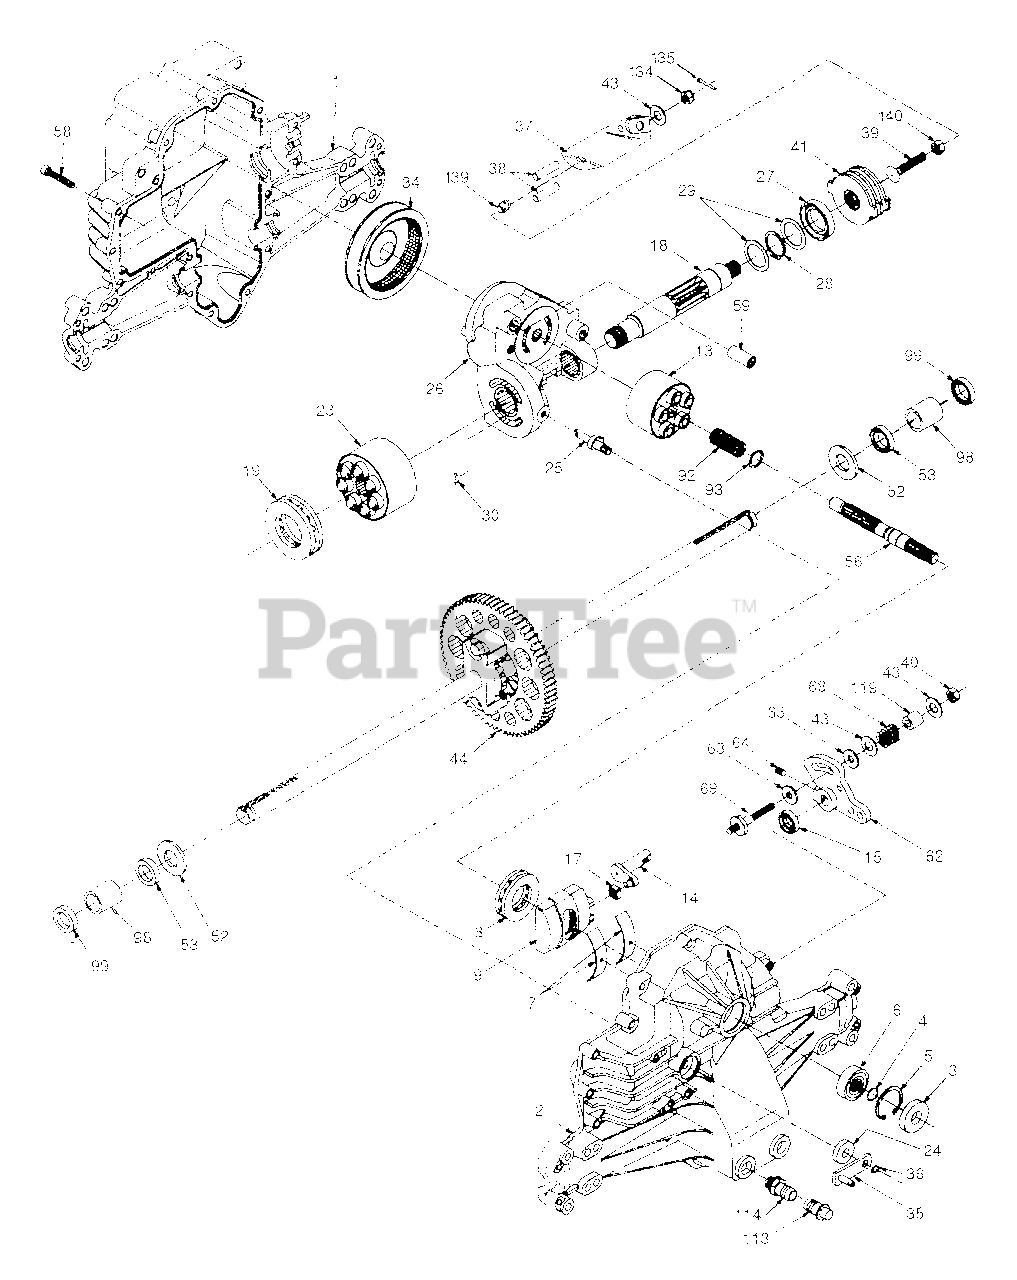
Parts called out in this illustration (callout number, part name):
1	Housing, Lower
2	Assembly, Upper Housing
4	Ring, Wire Retaining
5	Ring, Retaining
6	Bearing, Shaft Ball
7	Bearing, Cradle
8	Bearing, Thrust 30 x 52 x 13
9	Swashplate, Variable
13	Block, Cylinder Assembly
14	Arm, Trunnion
17	Guide, Slot
18	Shaft, Motor
19	Bearing, Thrust 42 x 68 x 16
23	Block, Cylinder Assembly
24	Seal, Lip 10 x 25 x 7
25	Actuator, Bypass
26	Center Section Assembly Kit
27	Seal, Lip 26 x 42 x 8
28	Ring, Retaining
29	Washer 26 x 35 x 1
34	Oil Filter Element
35	Arm, Bypass
36	Ring, Retaining
37	Arm, Actuating
38	Pin, Actuating
39	Bolt 5/16-24 x 1-3/4
40	Locknut, Hex 5/16-24 UNJC
41	Brake Rotor/Stator Kit
43	Washer 7/16 x 7/8 x .060
44	Differential Assembly
52	Washer 3/4 x 1.5 x .13
53	Seal .75 x 1.25 x .250
56	Shaft, Input
58	Bolt 1/4-20 x 1.38
59	Pin .5 OD x .43 ID x .750
62	Arm, Control
63	Puck, Dampener
69	Stud 5/16-24
92	Spring, Block
93	Washer, Block Thrust
98	Sleeve Bearing
99	Seal, Wiper
113	Cap, Vent Assembly
114	Fitting, O-Ring Assembly
119	Spacer
134	Nut, Castle 5/16-24
135	Pin, Cotter
139	Spring, Compression
140	Nut, Hex 5/16-24
